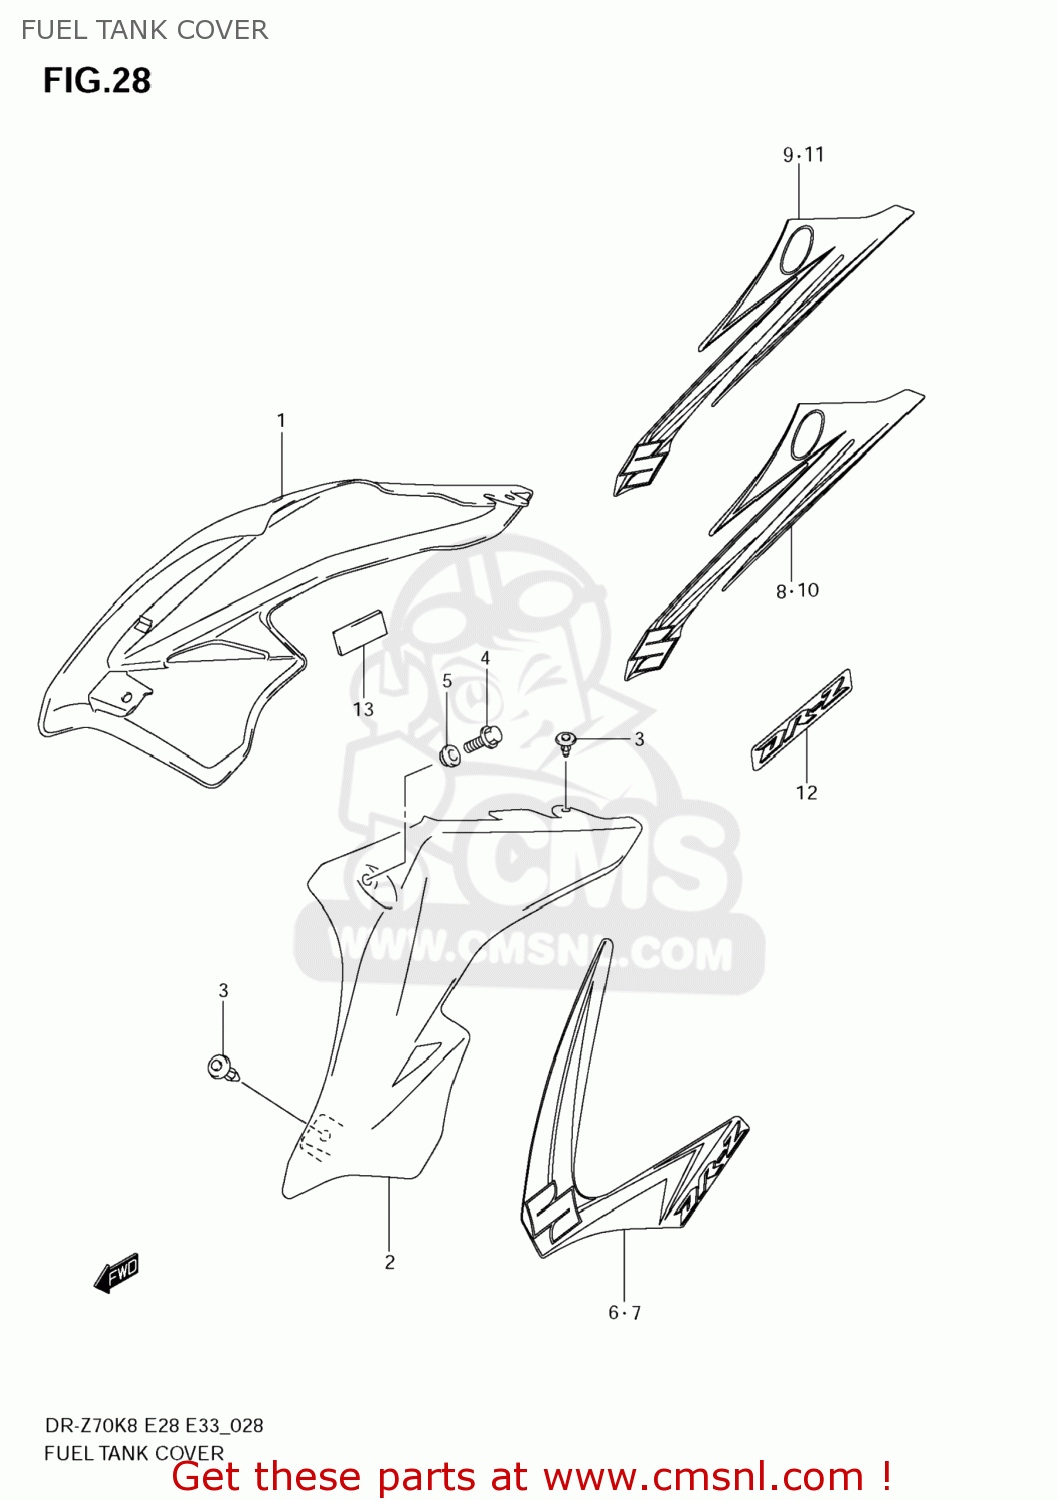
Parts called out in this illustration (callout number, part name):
1	COVER,FUEL TANK,R
2	COVER,FUEL TANK,L
3	CLIP(BLACK)
4	BOLT
5	WASHER
6	TAPE,FUEL TANK COVER,R
7	TAPE,FUEL TANK COVER,L
8	TAPE,FUEL TANK COVER,R
9	TAPE,FUEL TANK COVER,R
10	TAPE,FUEL TANK COVER,L
11	TAPE,FUEL TANK COVER,L
12	EMBLEM,FUEL TANK COVER
13	CUSHION,FUEL TANK COVER
